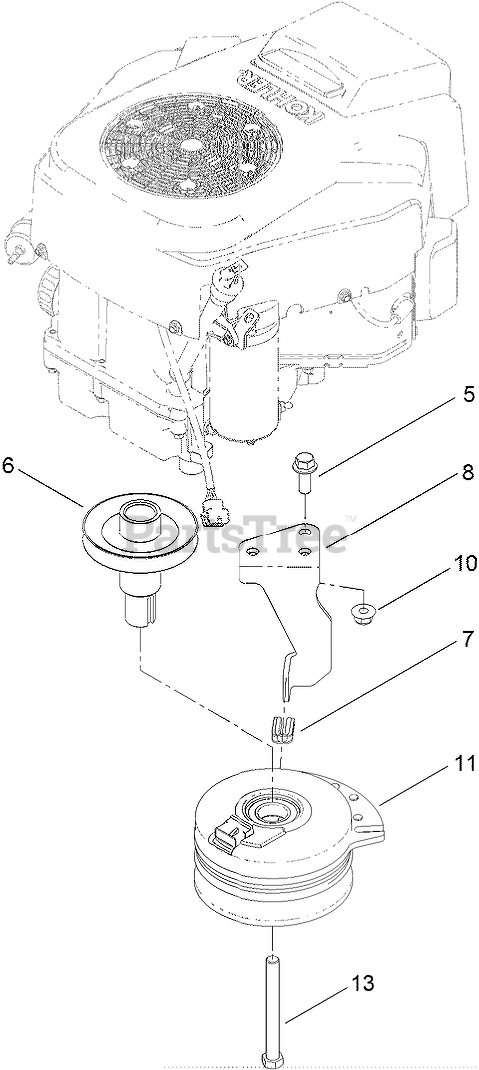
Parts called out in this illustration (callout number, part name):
5	SCREW-HHF
6	PULLEY-ENGINE
7	ISOLATOR-CLUTCH
8	STOP-CLUTCH
10	NUT-HF, NI
11	CLUTCH-ELECTRIC
13	SCREW-HH
